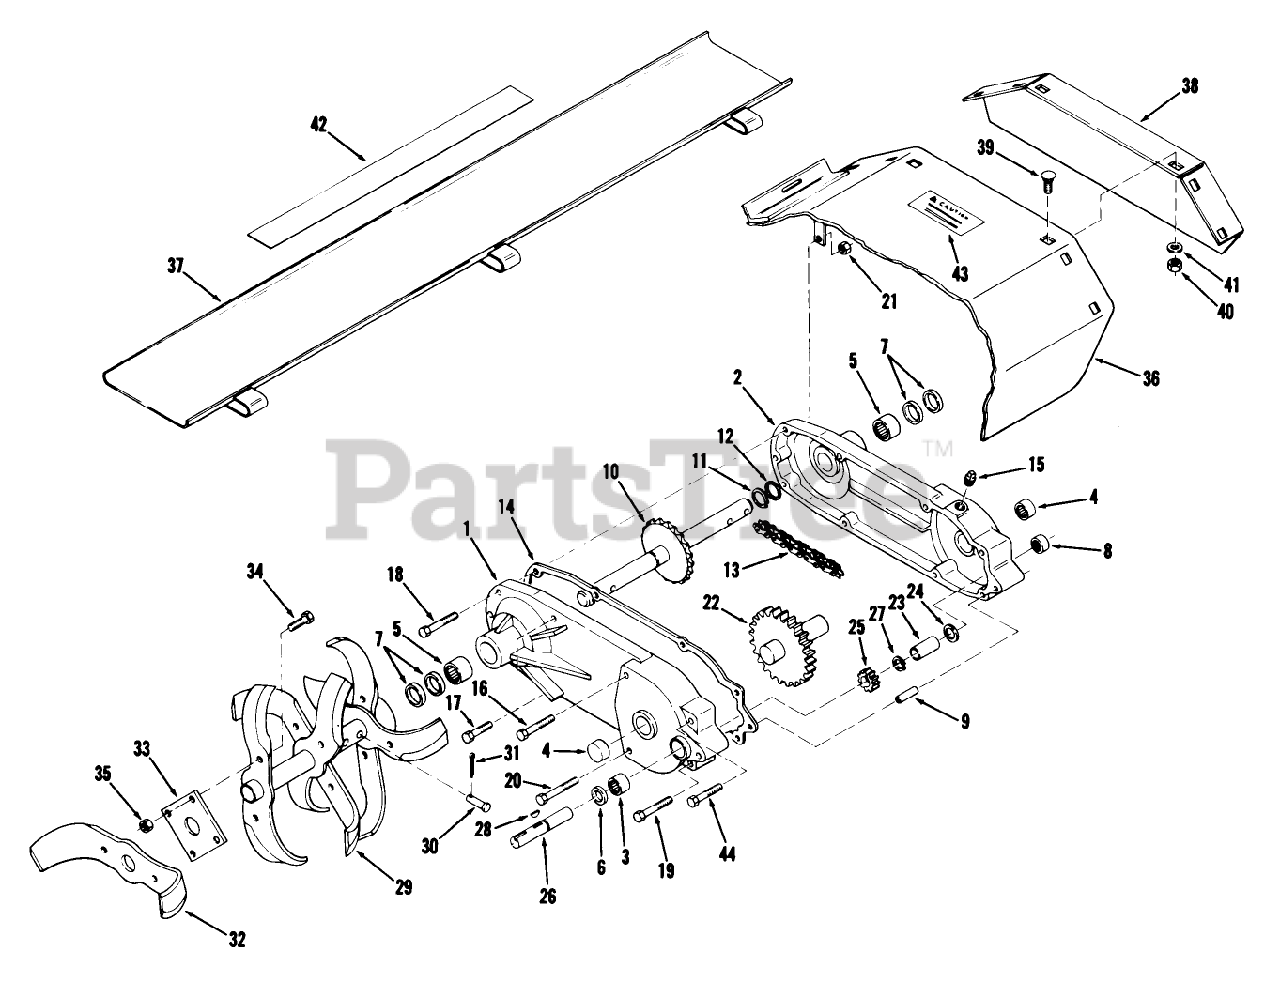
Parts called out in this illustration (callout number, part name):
1	R.H. Case (w/Bearings)
2	L.H. Case (w/Bearings)
3	BEARING-NEEDLE
4	BEARING-NEEDLE
5	BEARING-NEEDLE
6	SEAL-OIL
8	BEARING-NEEDLE
9	ROLL PIN 3/8 X 1
10	TINE SHAFT ASM
11	Snap Ring
12	WASHER
13	CHAIN
14	Gasket
15	SOLID PIPE PLUG
16	H H C S
17	Bolt
18	HHCS
19	BOLT
20	Hex Bolt
21	NUT
22	GEAR AND SHAFT ASM
23	Spacer
24	WASHER-THRUST
25	GEAR-PINION
26	SHAFT-INPUT
27	RING-SNAP, EXTERNAL
28	Key
29	Tine R.H.
29	Tine L.H.
30	PIN-CLEVIS
32	R.H. Tine
32	L.H. Tine
33	Plate-Tine Mounting
34	H H C S
35	Nut
36	X-REF 92-6514-01
37	Rear Shield
38	Cover-End
39	CARRIAGE BOLT -4
40	Nut
41	WASHER 5/16 SAE
42	DECAL-WHEEL HORSE
43	Caution Decal
44	Bolt 3/8-16 x 4
